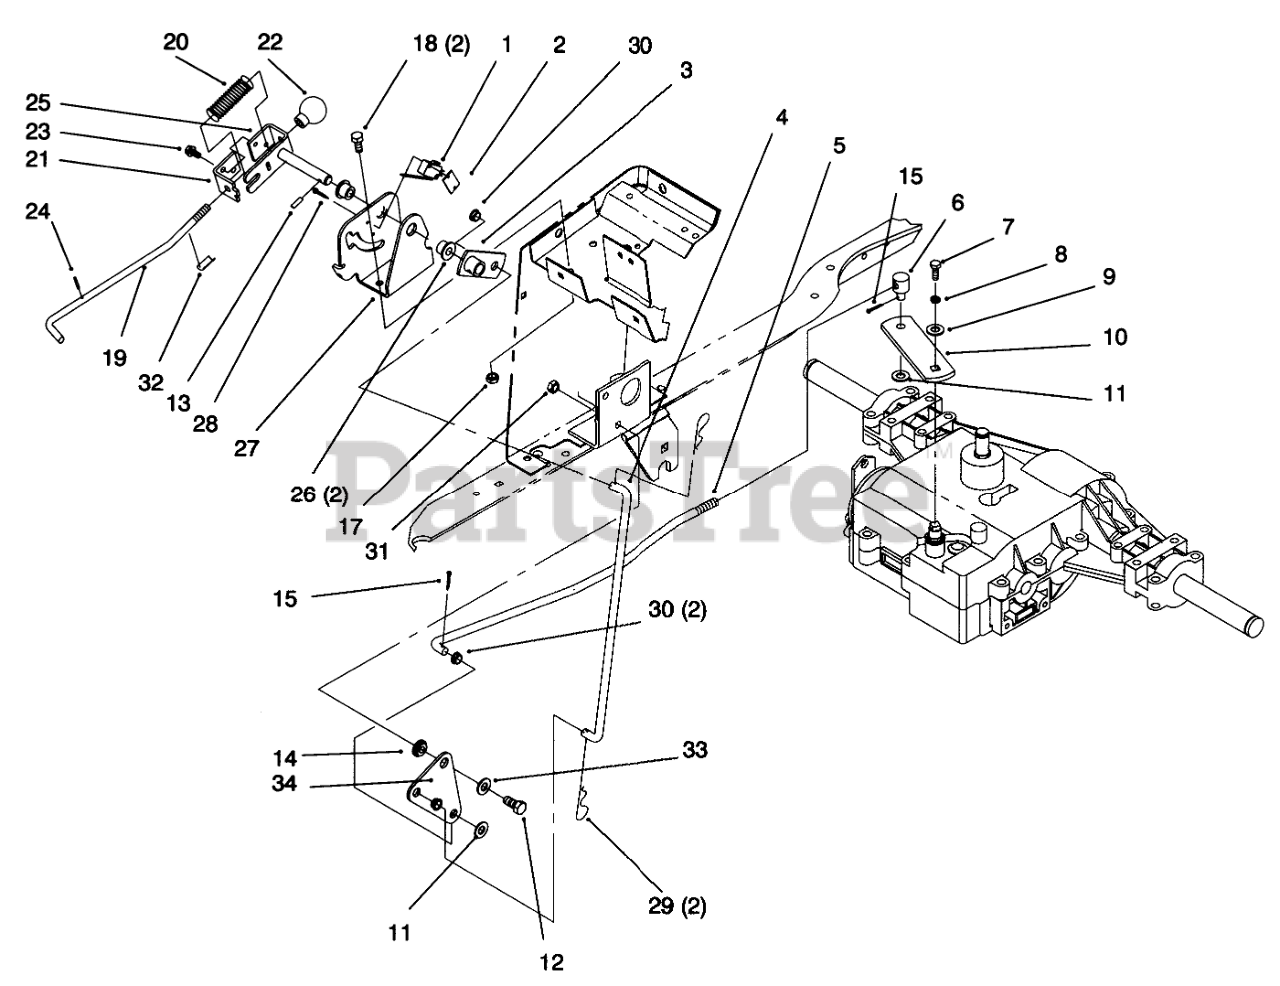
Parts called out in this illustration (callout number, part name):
1	Switch-Clutch (Only On: 72042, 72062)
2	Nut-Speed (Only On: 72042, 72062)
3	Tube-Linkage (Only On: 72042, 72062)
4	Rod (Only On: 72042, 72062)
5	Rod-Shift Transaxle (Only On: 72042, 72062)
6	Trunnion (Only On: 72042, 72062)
7	Screw (Only On: 72042, 72062)
8	Washer-Lock (Only On: 72042, 72062)
9	Spacer-Transmission (Only On: 72042, 72062)
10	Arm-Shift (Only On: 72042, 72062)
11	Washer-Flat (Only On: 72042, 72062)
12	Screw-HH (Only On: 72042, 72062)
13	Pin-Roll (Only On: 72042, 72062)
14	Bushing (Only On: 72042, 72062)
15	Pin-Cotter (Only On: 72042, 72062)
17	Nut-Lock (Only On: 72042, 72062)
18	Screw-HH (Only On: 72042, 72062)
19	Rod-Shift (Only On: 72042, 72062)
20	Spring-Compression (Only On: 72042, 72062)
21	Bracket-Shaft (Only On: 72042, 72062)
22	Knob (Only On: 72042, 72062)
23	Screw-TAP (Only On: 72042, 72062)
24	Pin-Roll (Only On: 72042, 72062)
25	Pivot-Shift (Only On: 72042, 72062)
26	Bushing (Only On: 72042, 72062)
27	Bracket-Pivot Mount (Only On: 72042, 72062)
28	Screw (Only On: 72042, 72062)
29	Pin-Cotter (Only On: 72042, 72062)
30	Bearing-Shift Link (Only On: 72042, 72062)
31	Nut-Lock (Only On: 72042, 72062)
32	Decal-Reverse Shift (Only On: 72042)
32	Decal-Reverse Shift (Only On: 72062)
33	Washer-Flat (Only On: 72042, 72062)
34	Bracket-Pivot (Only On: 72042, 72062)
